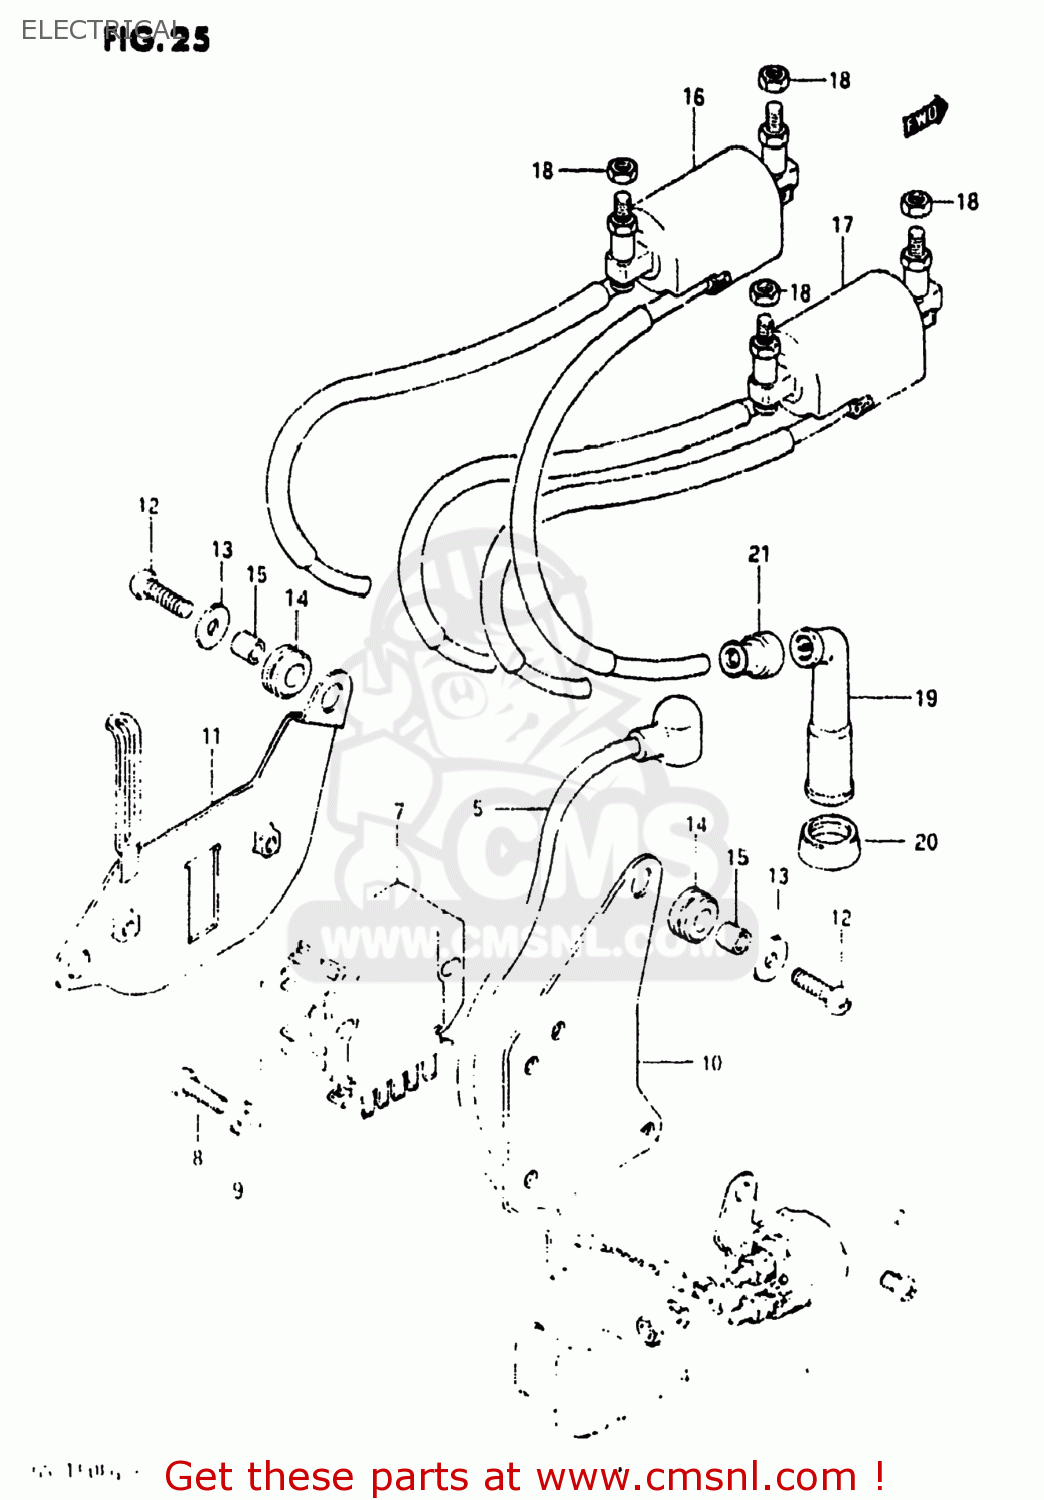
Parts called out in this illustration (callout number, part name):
1	RELAY ASSY,STARTING MOTOR
2	SCREW
3	NUT
4	WASHER,LOCK
5	WIRE,STARTER MOTOR LEAD
6	CAP,STARTER RELAY TERMINAL
7	RECTIFIER ASSEMBLY
8	SCREW
9	WASHER, LOWER
10	HOLDER COMP,ELECTRONIC PARTS
11	PLATE,ELECTRIC PARTS H
12	SCREW
13	WASHER
14	CUSHION
15	SPACER (6.3X9.1X6.7)
16	COIL ASSEMBLY,IGNITION
17	COIL ASSEMBLY,IGNITION
18	NUT
19	CAP,SPARK PLUG
20	SEAL,SPARK PLUG CAP
21	SEAL,SPARK PLU
